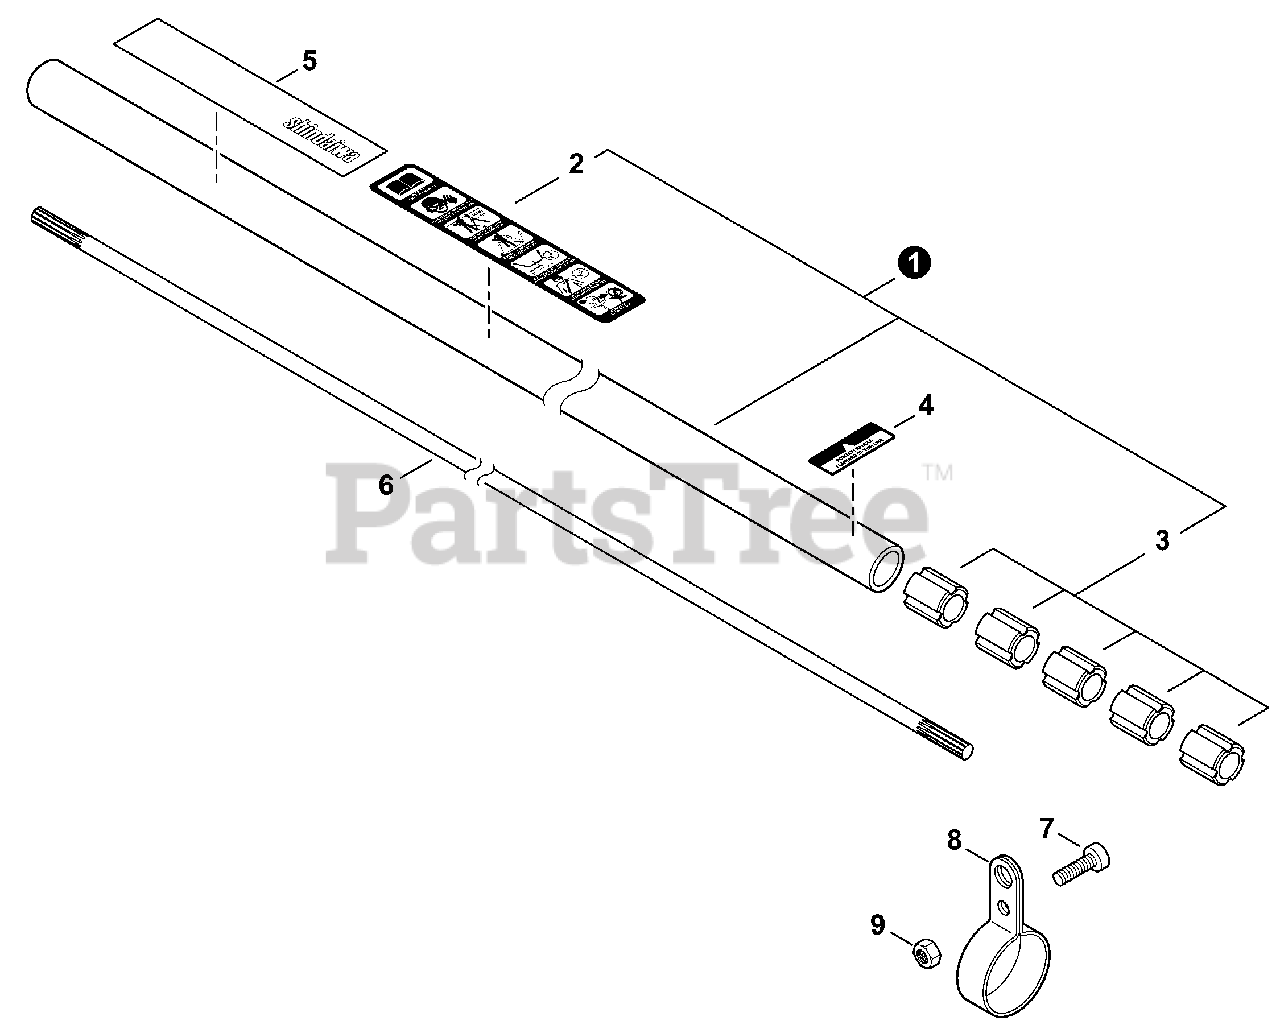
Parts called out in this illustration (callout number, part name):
1	MAIN PIPE ASSY
2	LABEL, CAUTION (BLADE CAPABLE)
3	BUSHING
4	LABEL, HANDLE
5	LABEL, SHINDAIWA PROFESSIONAL
6	MAINSHAFT
7	BOLT 5×12
9	NUT M5
